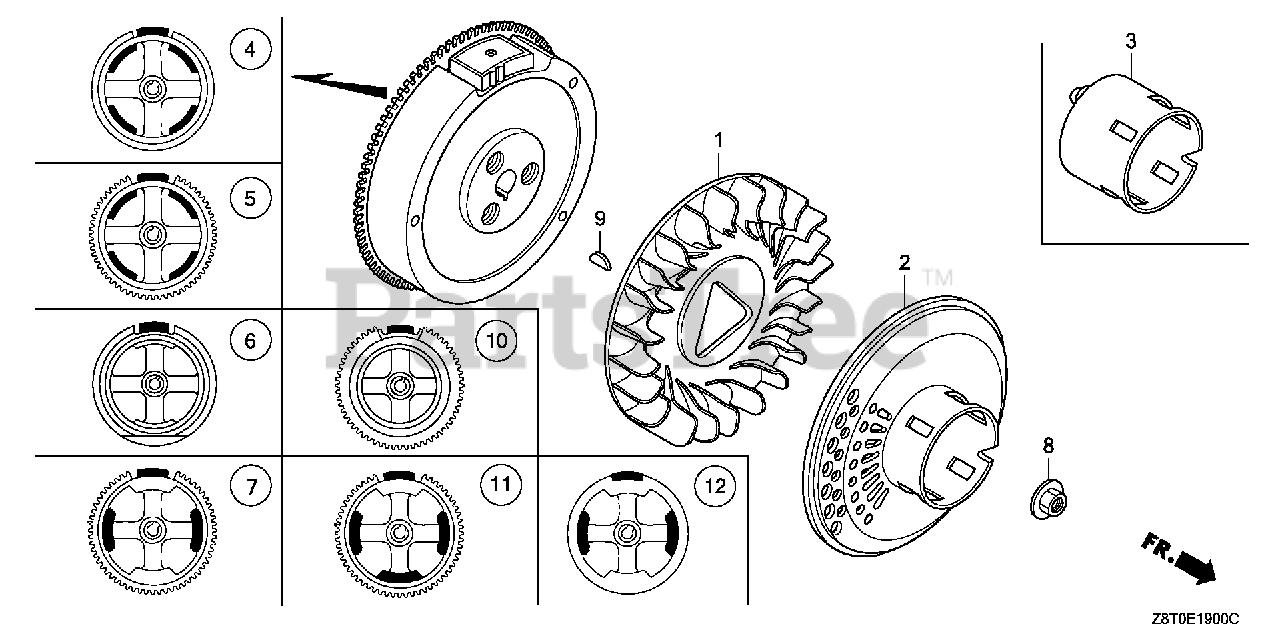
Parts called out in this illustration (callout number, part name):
1	FAN, COOLING
2	PULLEY, STARTER (SCREEN GRID)
5	FLYWHEEL (SEL-4POLE)
8	NUT, SPECIAL (16MM)
8	NUT, SPECIAL (16MM) (1)
9	KEY, SPECIAL WOODRUFF (25X18)
